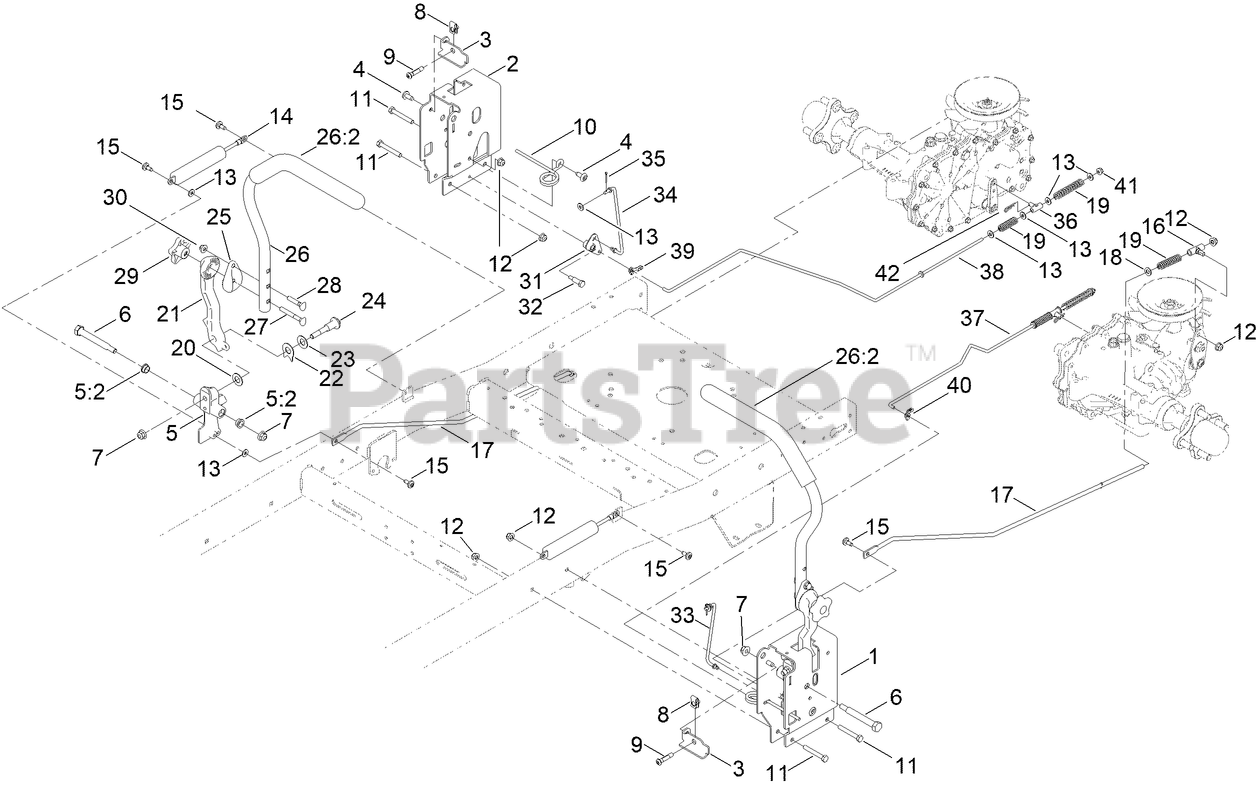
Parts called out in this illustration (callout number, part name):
1	CONTROL BOX - LH G7
2	CONTROL BOX - RH G7
3	ADJUSTMENT PLATE-CONTROL BOX
5	PIVOT ARM ASM
5:2	BUSHING-FLANGE
6	BOLT-PIVOT
7	NUT-HF, NI
9	SCREW-HSBH
10	SPRING-TORSION
11	SCREW-HH
12	NUT-HF, NI
13	WASHER
14	DAMPER-NON CAVITATING
15	SCREW-SHOULDER
16	MOUNT-ROD, HYDRO
17	ROD-HYDRO
18	WASHER-PLAIN
19	SPRING-COMPRESSION
20	WASHER-NYLON
21	ARM-CONTROL, 32 TEETH
22	SPACER, ANTI-ROTATION
23	WASHER-BELLEVILLE
24	BOLT-PIVOT
25	DISC-ADJUSTMENT HANDLE, 32 TEETH
26	HANDLE-CONTROL,
27	SCREW-HANDLE
28	SCREW-HANDLE
29	KNOB-HANDLE
30	NUT-HF
31	BELLCRANK
32	BOLT - SHOULDER
33	LINK-BRAKE, LH
34	LINK-BRAKE, RH
35	PIN-COTTER
36	MOUNT-PIVOT
37	ROD-BRAKE LH
38	ROD-BRAKE, RH
39	CLIP, ROD, RH, 7R, 1/4IN
40	CLIP, ROD, LH, 7L, 1/4IN
41	NUT-FLANGE, NI
42	PIN-HAIR
